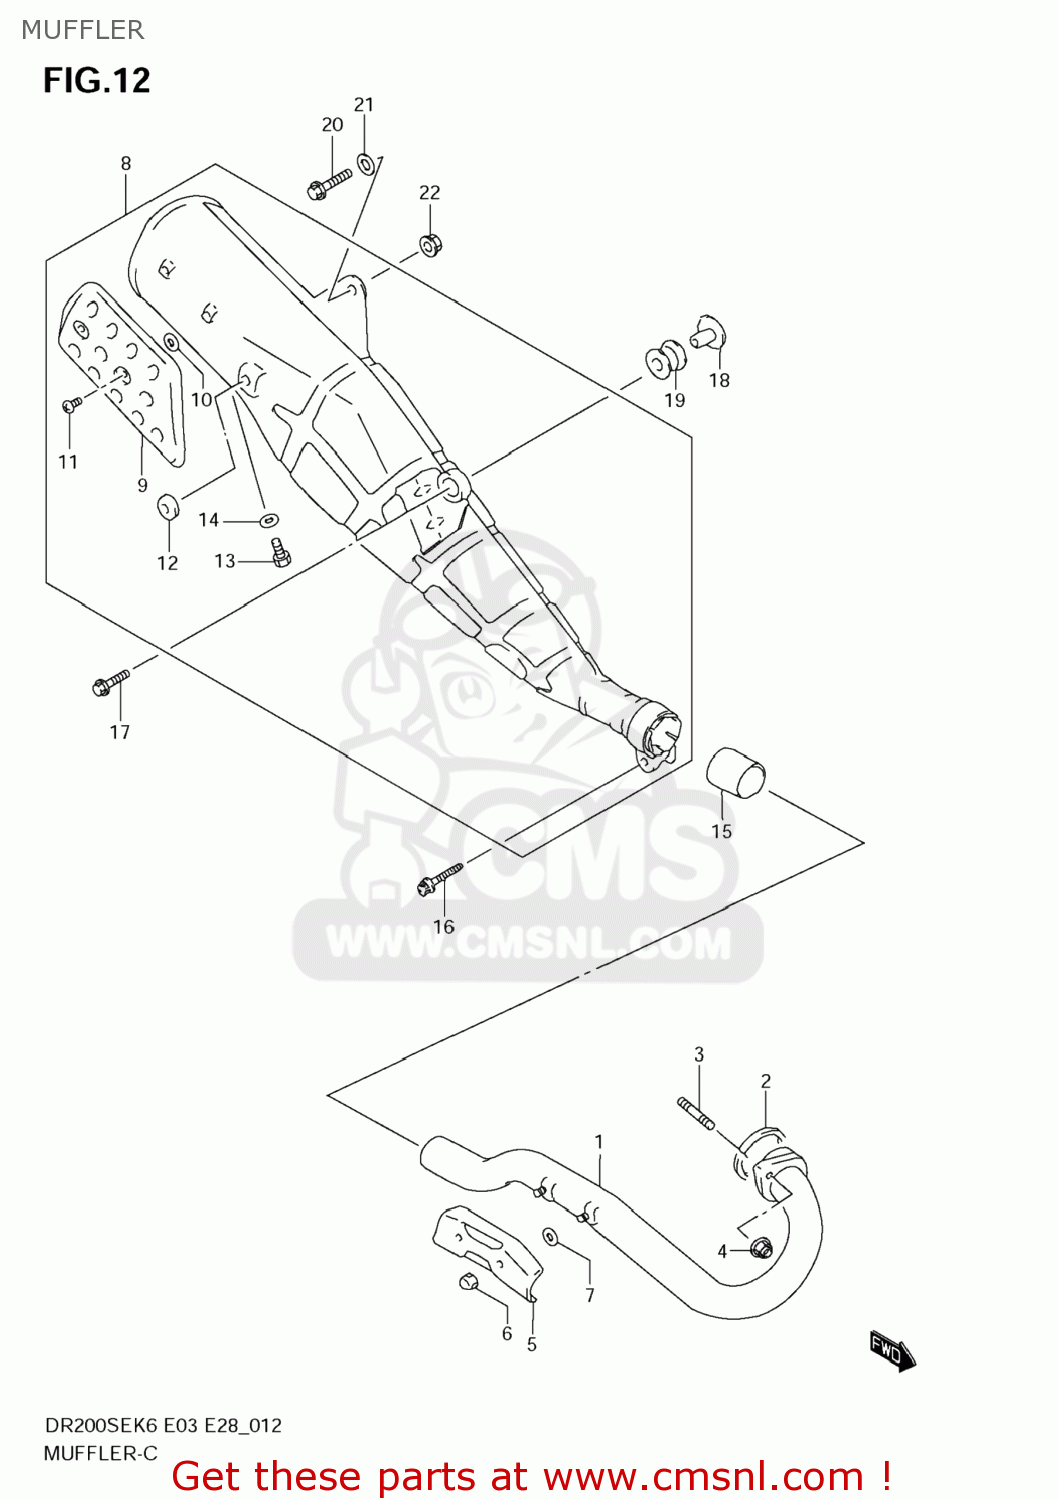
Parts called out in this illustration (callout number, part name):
1	PIPE,EXHAUST
2	GASKET,EXHAUST PIPE (NAS)
3	BOLT,STUD
4	NUT
5	COVER,EXHAUST PIPE
6	NUT
7	GASKET(6X16X1.4) (NAS)
8	MUFFLER ASSY
9	COVER,MUFFLER
10	GASKET(5.8X13X1.4) (NAS)
11	SCREW(6X10)
12	CUSHION
13	PLUG(12X9)
14	GASKET(12.1X16.2X3.7) (NAS)
15	GASKET,2ND MUFFLER (NAS)
16	BOLT
17	BOLT(8X35)
18	SPACER(8.6X12X17.5)
19	CUSHION
20	BOLT(8X35)
21	WASHER
22	NUT
